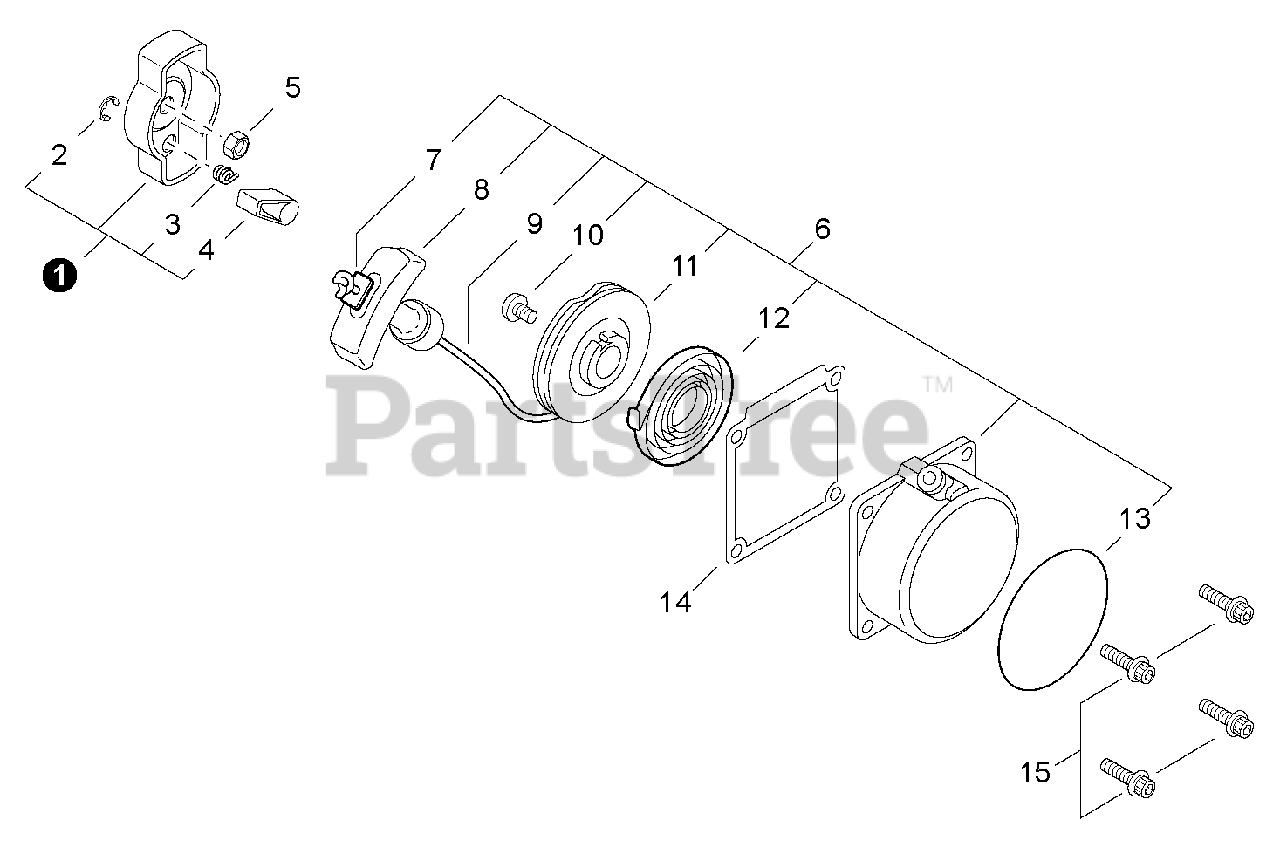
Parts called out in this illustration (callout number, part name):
1	STARTER PAWL ASSY
2	RING, RETAINING - 4
3	SPRING, RETURN
4	PAWL, STARTER
5	NUT - 8
6	STARTER ASSY
7	ROPE, STARTER
8	GRIP, STARTER
9	ROPE, STARTER
10	SCREW - 5
11	REEL, ROPE
12	SPRING, REWIND
13	LABEL - TRADE
14	GASKET, STARTER
15	SCREW - 4X16
